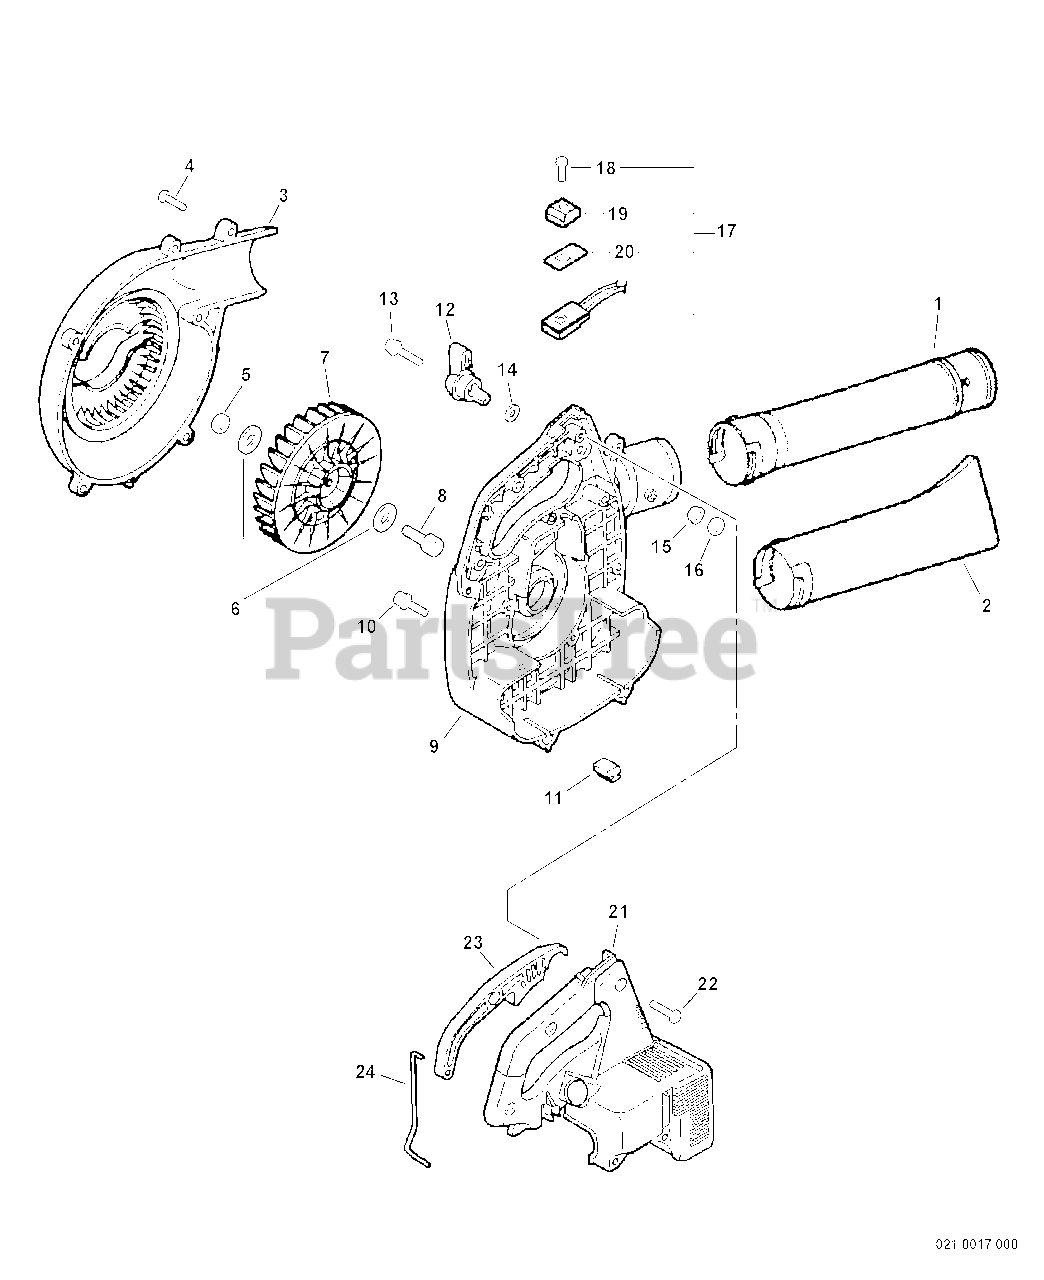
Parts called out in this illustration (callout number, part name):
1	TUBE, BLOWER - STRAIGHT
2	TUBE, BLOWER - NOZZLE
3	COVER, FAN
4	SCREW, TAPPING 5×20
8	HUB, FAN
9	COVER, FAN - OUTER
10	SCREW 4×22
12	CONTROL, THROTTLE
13	SCREW 5×25
14	WASHER 5.5×12×0.8
15	NUT, FLANGE M5
17	CABLE ASSY, CONTROL
18	SCREW 3×10
19	KNOB, SWITCH - ORANGE
20	LABEL, SWITCH
21	COVER, ENGINE
22	SCREW, TAPPING 5×20
23	CONTROL, THROTTLE
24	ROD, THROTTLE
